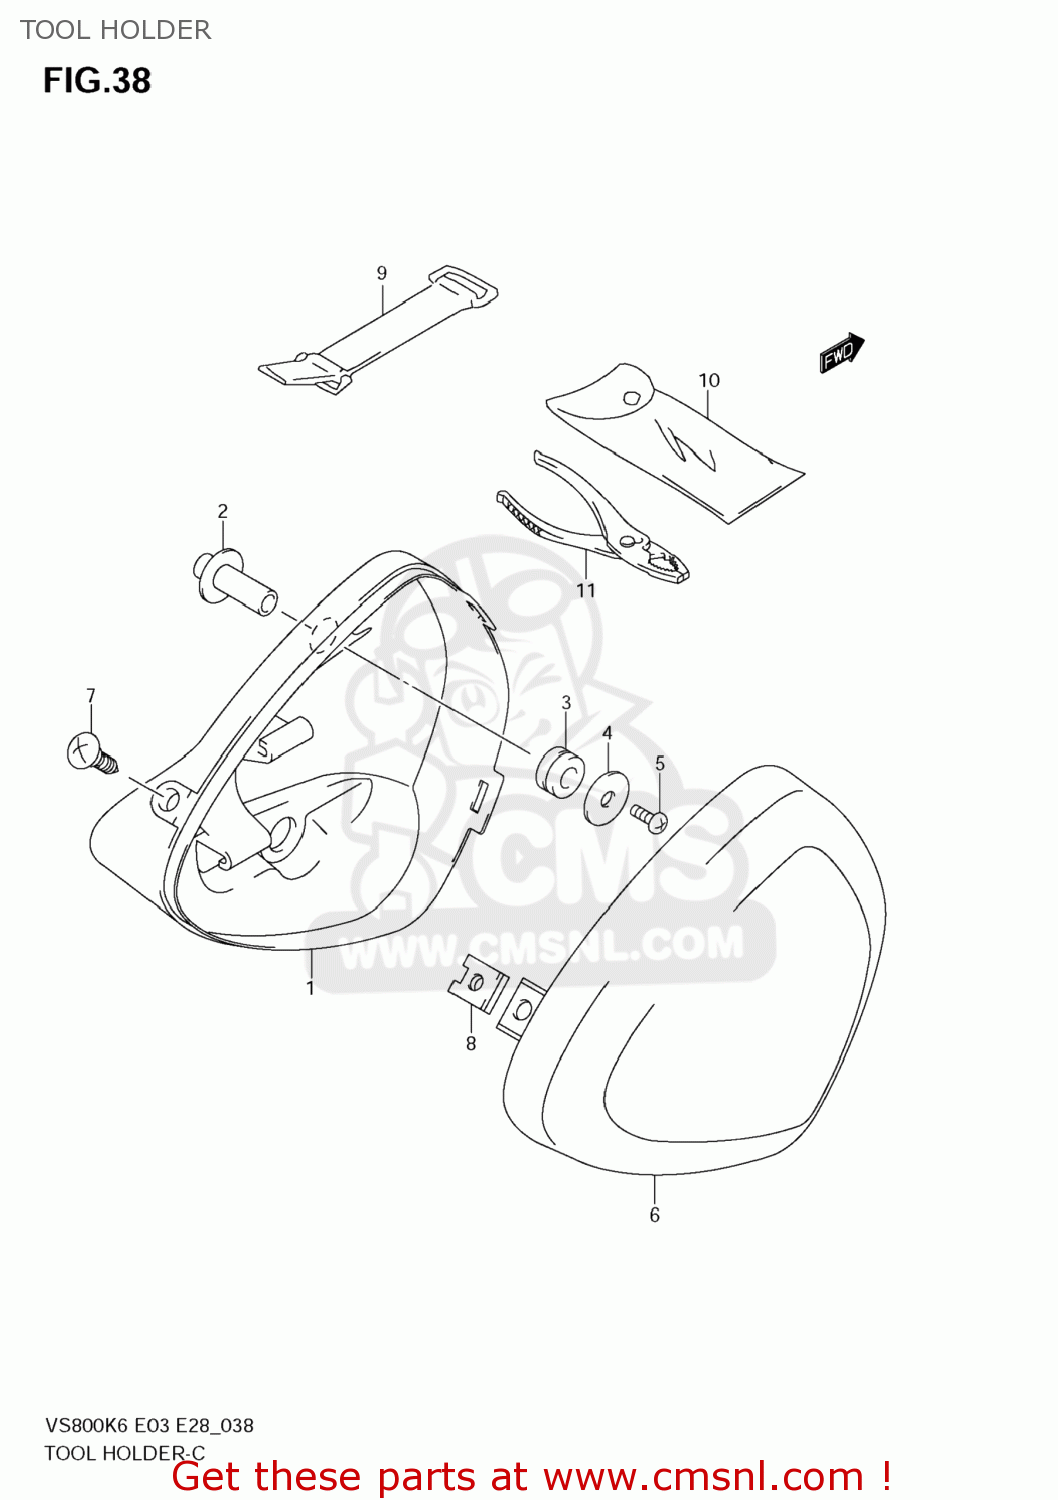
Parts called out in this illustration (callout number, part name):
1	BOX, LUGGAGE V
2	SPACER,TOOL HOLDER
3	CUSHION
4	WASHER(6.5X22X1.6)
5	SCREW
6	CAP,TOOL HOLDER
7	SCREW(6X23)
8	NUT
9	BAND
10	TOOL ASSY
11	PLIER(150)
